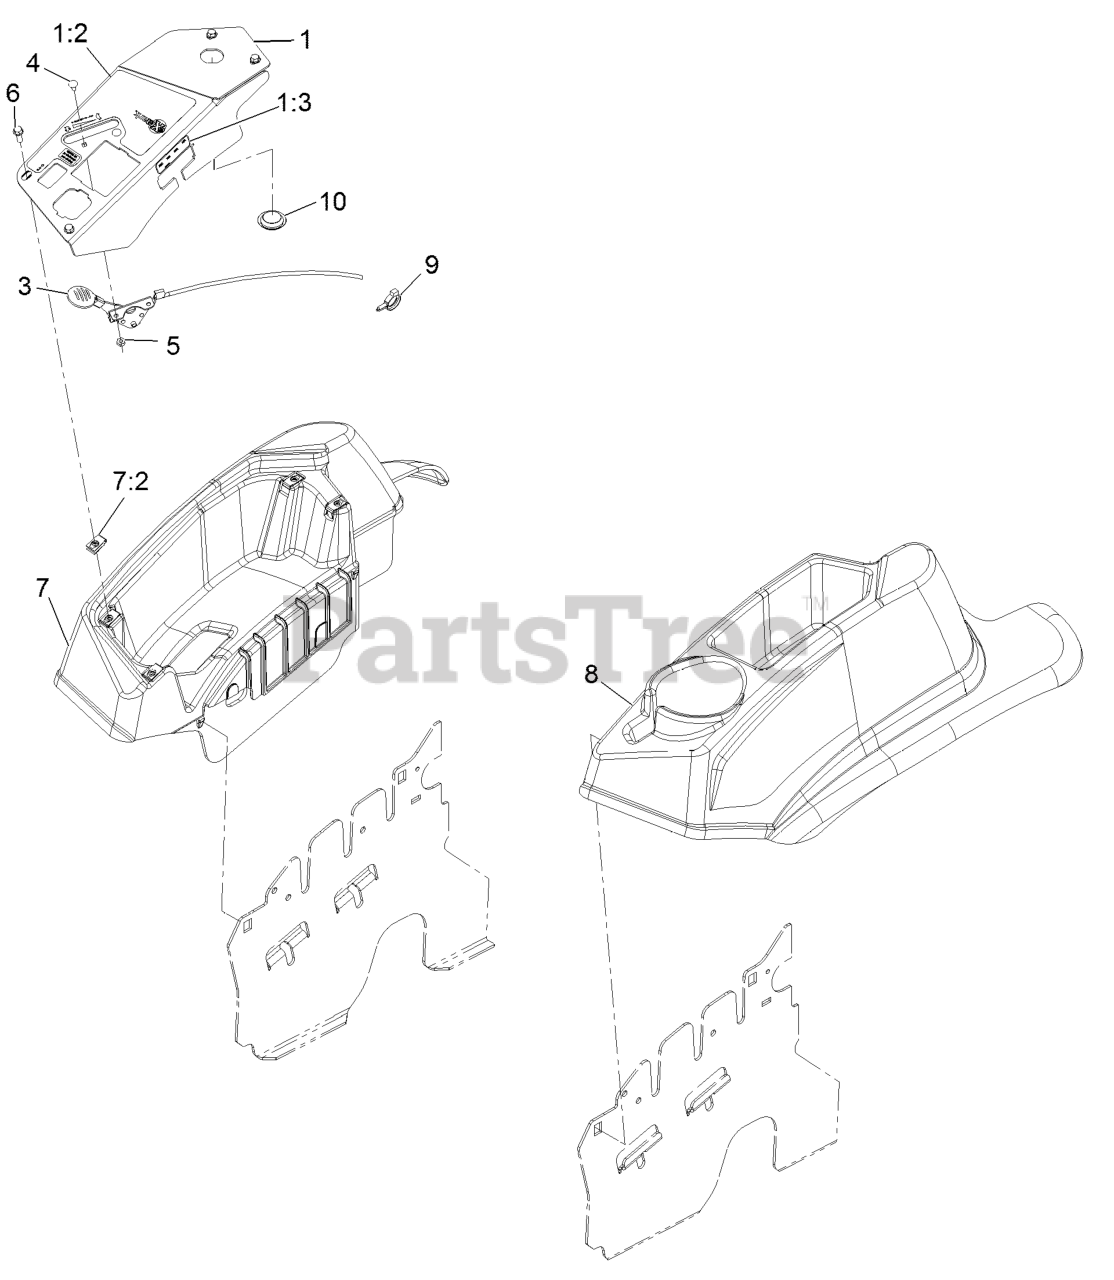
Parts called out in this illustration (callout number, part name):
1	CONTROL PANEL W/DECALS AS
1:2	DECAL,CONTROL PANEL LP
1:3	DECAL-FUSE
3	ASM,THROTTLE CABLE
4	BOLT-CARR
5	NUT-LOCK, NI
6	SCREW-HWH
7	CONSOLE,RH AS ASM
7:2	Nut-Retainer-Panel 1/4-20
8	CONSOLE, LH AS
9	CLAMP-HOSE
10	PLUG-PLASTIC
